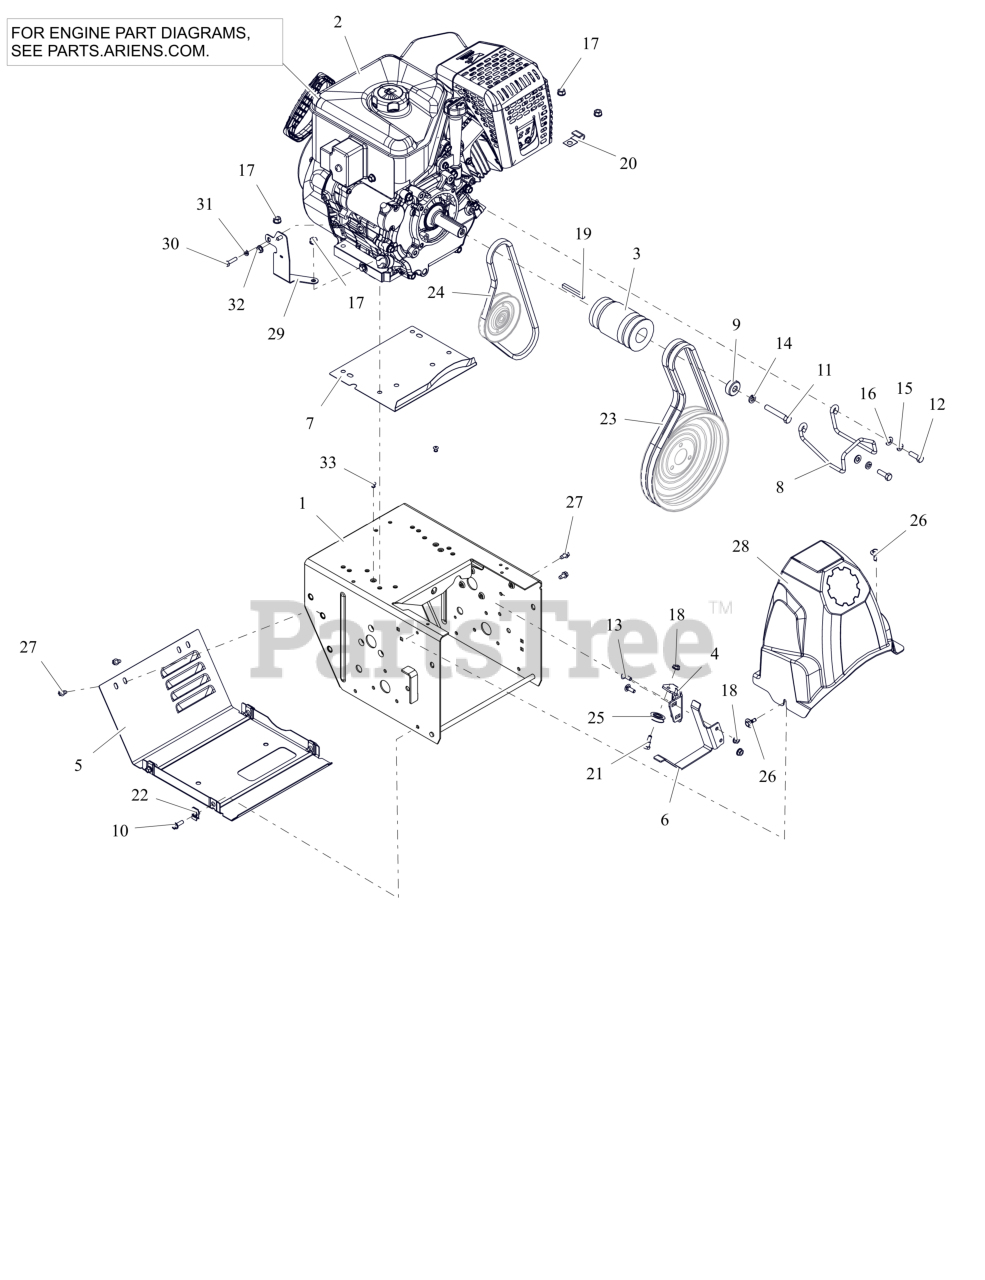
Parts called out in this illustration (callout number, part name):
1	FRAME, MAIN - PRO (WELDMENT)
2	ENGINE,EFI420 GEN3 120V/60W
3	SHEAVE, COMBO HYDRO WHEEL 4L
4	BRACKET, CLUTCH CABLE
5	COVER, BOTTOM - VENTILATED
6	FINGER, BELT - FLAT
7	BAFFLE, WATER - LARGE BLOCK
8	FINGER, BELT
9	BSHG, SPCR .406 X 1.250 X .500
10	BLT, HWH .25-20X.75 G5 ZCC
11	BLT, HEX .38-24X2.25 G5 ZCC
12	BLT, HEX 0.3125-24X1 G5 ZCC
13	BLT, RHSN .25-20X.750 G5 ZCC
14	WSHR,LK-REG .375X.094 ZCC
15	WSHR, LK-HVY .312X.097 ZCC
16	WSHR,FLT .344X.688X.065 ZCC
17	NUT,LK-CTR-FLG .31-18 GF ZCC
18	NUT-LK-TOP-FLG .250-20 GF ZCC
19	KEY .25X.25X2.25
20	J-CLAMP
21	BOLT, SHLDR -.375 X .375 X .25-20
22	NUT-RTNR .25-20X.56
23	V-BELT, HA-RAW EDGE (SET)
24	V-BELT, 4L-WRAPPED
25	PULLEY, CABLE
26	SCR-TAP .25-20X.5 CAPTIVE
27	SCR-TAP .25-20X.50 HWH ZCC
28	COVER, BELT
29	WLDMT- LG BLOCK FUSE MOUNT
30	BLT,HEX M6-1X25 G8.8 ZC120
31	WSHR,LK-REG .250X.062 ZCC
32	NUT-LK-CTR-FLG .25-20 ZC120
33	RVT, POP .1875 ZCC
